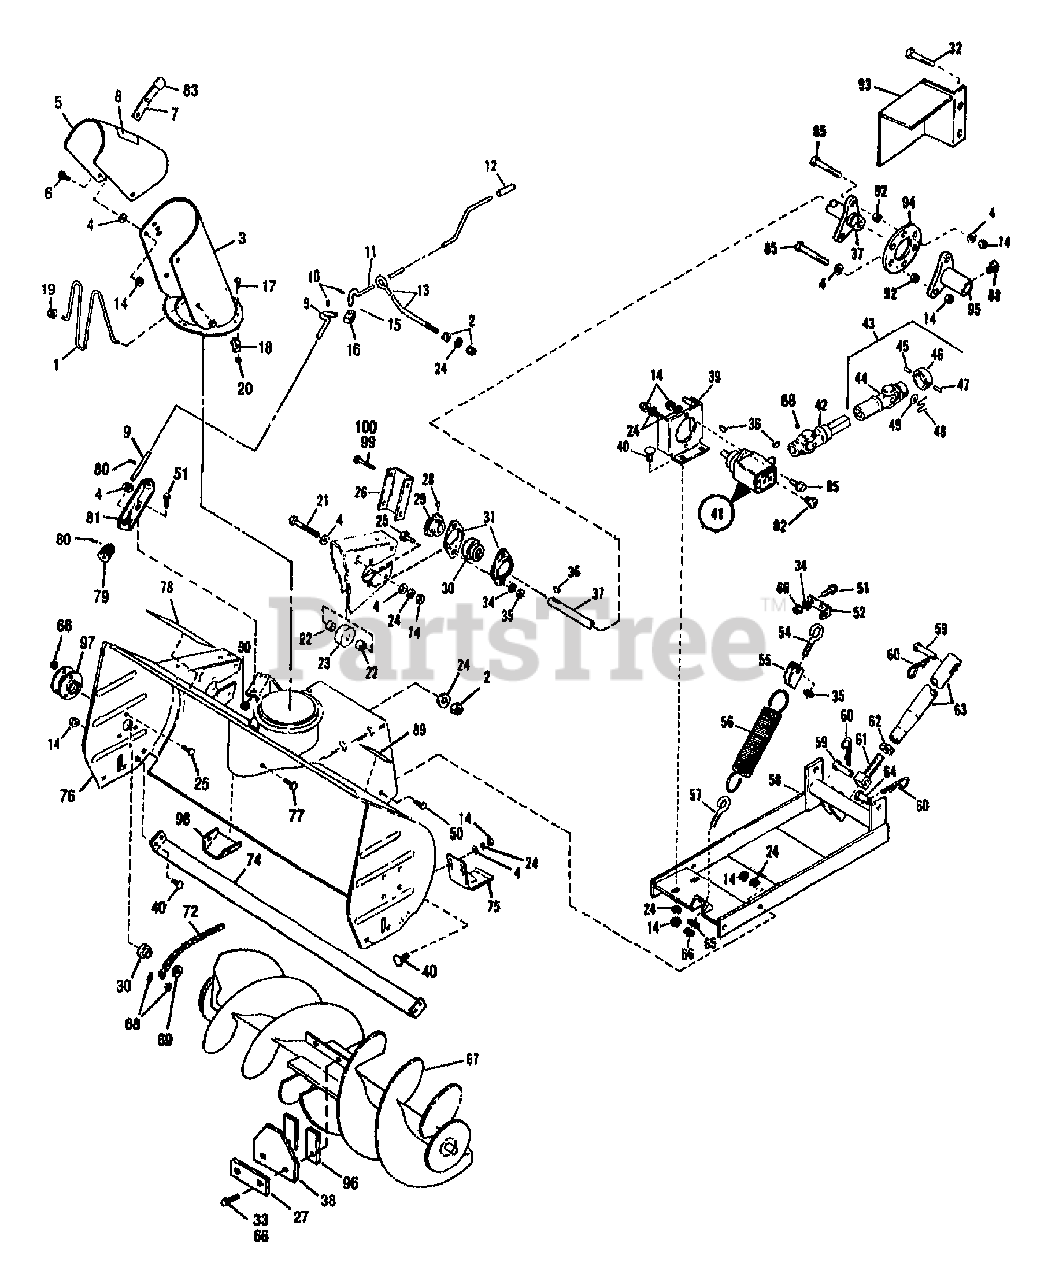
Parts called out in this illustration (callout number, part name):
1	GUARD-CHUTE
2	NUT-HEX 3/8-16 ZP
3	ASSM-DISCHARGE CHUTE
4	WASHER-FLAT 3/8 SAE
6	SCR-HH 3/8-16X.75 G5 ZP
7	LEVER-ADJUSTING
8	DECAL-WARNING
9	SHAFT-PINION
10	PIN-ROLL 1/8 X 3/4
12	GRIP-PLASTIC
13	SCR-EYE
14	NUT-LOCK 3/8-16
15	PIN-COTTER .125 X .75 ZP
16	BLOCK-SWIVEL NYLON
17	SCR-SEMS MACH
18	CLIP-HOLD DOWN
19	NUT-PUSH 3/16
20	NUT-H/LK M10-24 NYLOCK
21	SCR-HH 3/8-16X3.0 G5 ZP
22	SPACER-.68X.39X.46
23	BLOCK-TENSION
24	WASHER-LK .375 @ DEPL
25	SCR-CARR 5/16-18X.75 G2 ZP
27	PLATE
28	SCR-SET
30	BEARING-BALL
31	BEARING-FLANGE
32	SCR-HH 3/8-16X1.0 G5 ZP
33	SCR-HFLK 5/16-18X1.25 ZP
34	WASHER-LK .312 ZP
35	NUT-HEX 5/16-18 ZP
36	KEY-WOODRUFF .188X.75
37	SHAFT-DRIVE
39	ASSM-SUPPORT
40	SCR-CARR 3/8-16X1.00
42	JOINT-U
43	ASSM-U JOINT ASC
50	SCR-HFLK 3/8-16X1.00 ZP
51	SCR-HFLK 5/16-18X.75 ZP
52	ANCHOR-SPRING
55	BRKT-SPRING
56	SPRING-EXT
59	PIN-CLEVIS .5X2.25
60	PIN-HITCH .125X2.56 ZP
61	ADJ-LIFT LINK
62	NUT-HEX
64	PIN-CLEVIS .625 X 1.38
65	WASHER-FLAT 5/16 SAE
66	NUT-TOP/LK 5/16-18 ZP
67	ASSM-ROTOR 38"
68	LINK-CONNECTOR
69	WASHER-THRUST 1.1X.76X.05
72	CHAIN-DRIVE
74	SCRAPER
75	SHOE-SKID
76	ASSM-ROTOR HSG W/DECAL
77	SCR-HH 3/8-16X.50
78	DECAL-LOGO
79	GEAR-WORM LH
80	PIN-DRIVE .09X.75
81	SUPPORT-SHAFT
82	VALVE
85	SCR-HH 3/8-16X1.25
88	SCR-SET SQ 5/16-18X5/8
89	DECAL-WARNING
90	NUT-HFLK 5/16-18 ZP
92	NUT-JAM
94	DISC-COUPLING
95	ASSM-HUB
96	SLINGER EXTENSION
98	ASSM-DEFLECTOR
99	SCR-HH 1/4-20X3.0 G5 ZP
100	NUT-HT LK 1/4-20
